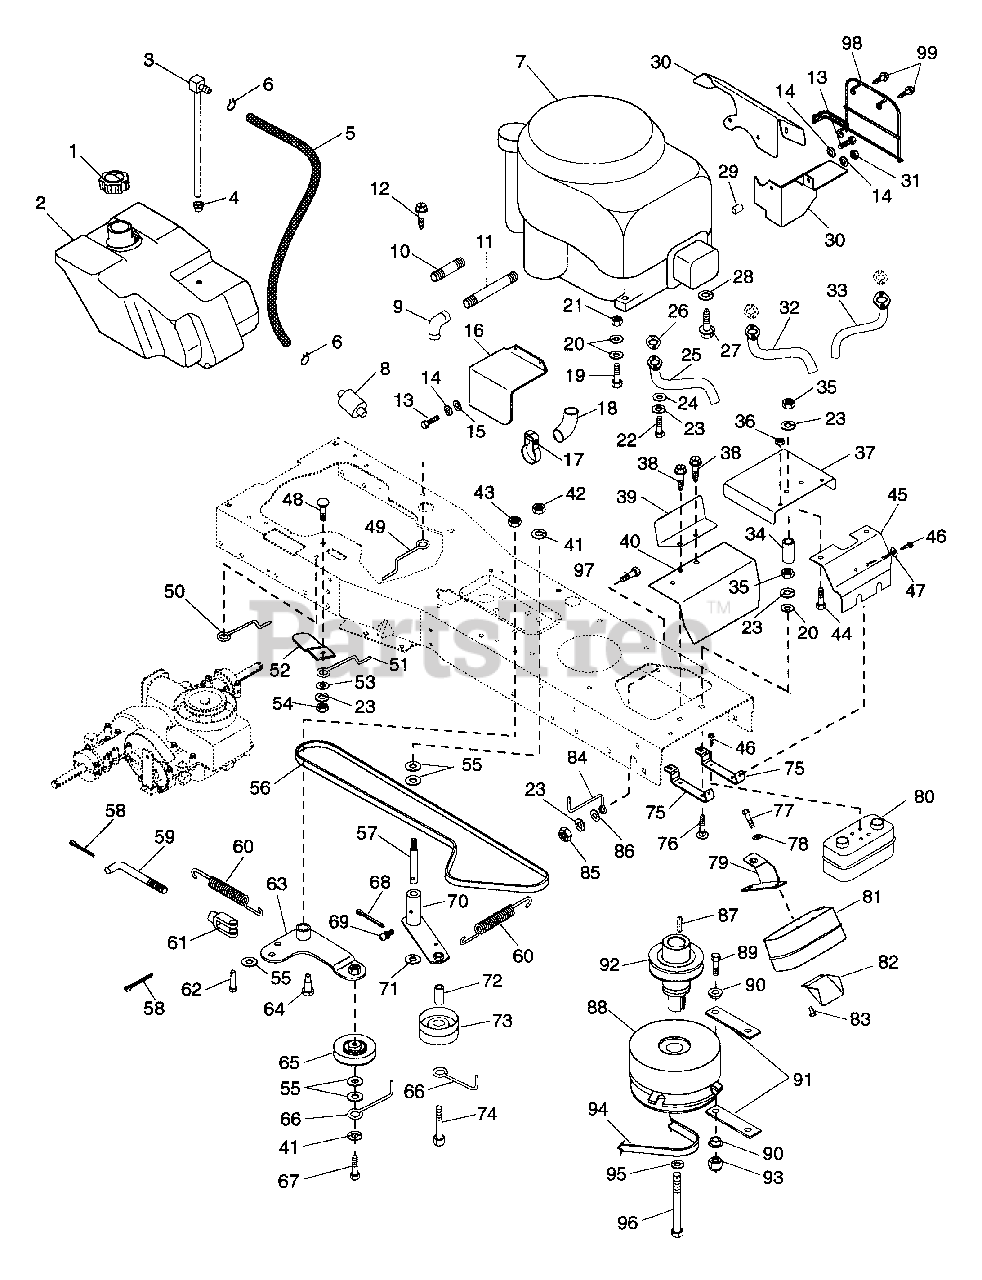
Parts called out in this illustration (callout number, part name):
1	FUEL CAP
2	FUEL TANK
3	TANK FITTING
4	BSHG-FLG .375 X 1.062 X .625 R
5	HOSE- FUEL LINE 34.00"
5	HOSE- FUEL LINE 40.50"
6	CLAMP-HOSE WIR.490/.510X.092#8
7	ENGINE- 12.0 OHV TEC
7	ENGINE- 14.0 OHV B&S I/C QUIET
7	ENGINE- 13.0 TEC OHV
7	ENGINE- 15 TEC OHV
7	ENGINE- 16.5 TEC OHV
7	ENGINE- 16.0 B&S VANGUARD TWIN
7	ENGINE- 12.0 B&S I/C
8	FUEL FILTER
9	ELBOW .375-18 NPTF
10	NIPPLE
11	NIPPLE
12	SCR-TAP .312-18X.75 HWH PL TR
13	BLT-HEX .25-20X.75 PL GR2
14	WSHR-LK .250X.077 HVY PL
15	WSHR-FL-STL.312X.734X.065PL
16	HEAT SHIELD
17	CLAMP, MUFFLER 1.38
18	PIPE
19	BLT-HEX .31-18X1.50 PL GR5
20	WSHR-FL-STL .328X.875X.062 PL
21	NUT-LK-TOP .312-18 GR C PL
22	SCR-CAP .31-18X.75 S/HD
23	WSHR-LK .312X.097 PL HVY
24	WSHR-FL-STL .323X.625X.062 PL
25	EXHAUST TUBE WELDT- 12.5/13HP
25	EXHAUST TUBE WELDT- 15/16.5HP
26	GASKET- 12.5/13 TEC (#35-414)
26	GASKET:15-16.5HP TEC (#35-438)
27	SCR-TAP .375-16X1.25 HWH PL TR
28	WSHR-LK-EXT .375X.050
29	SPACER BUSHING .5 X .32 X .21
30	HEAT SHIELD- SIDE 12B&S
30	HEAT SHIELD
31	NUT-HEX .250-28 YWZC
32	PIPE- EXHAUST R.H.
33	PIPE- EXHAUST L.H.
34	SPACER .334X.500X1.12
35	NUT-HEX .312-18
36	NUT-LK-CTR .250-20 PL
37	SHIELD- REAR HEAT 16B&S
38	SCR-TAP .312-18X.75 HWH PL TR
39	SHIELD
40	HEAT SHIELD
41	WSHR-LK .375X.094 MED PL
42	NUT-HEX .375-16
43	NUT-LK-CTR .375-16 GR A PL
44	BLT-HEX .25-20X.50 PL GR5
45	SHIELD- FRONT HEAT 16B&S
46	SCR-TAP 12-24X.50 HWH PL TR
47	WSHR-FL-STL.281X.62X.065 PL
48	BLT-RDHDSQNK .31-18X1.00 PL
49	BELT FINGER
50	BELT FINGER
51	BELT FINGER
52	BRACE
53	WSHR-FL-STL.344X.688X.065PL
54	NUT-HEX .312-18
55	WSHR-FL-STL .390X.750X.125 PL
56	V-BELT, HA-WRAPPED
56	V-BELT, 4L-RAW EDGE
57	SHOULDER STUD
58	PIN-COTR .09X.75 PL
60	SG-TENS .091X.56X5.07 WLD 30
61	YOKE, .312-24 X 2.25
62	PIN-CLEV .312X.822 HDND PL
63	IDLER PIVOT ARM
64	BLT-SHLDR .38-16X1.25
65	IDLER-V 3X.38
66	FINGER - BELT
67	BLT-HEX .38-16X1.75 PL GR2
68	PIN-COTR .18X1.25 PL
69	FTG-LUBE .25-28X.256 YWZC
70	IDLER PIVOT ARM
71	WSHR-FL-STL .520X.827X.062 YZ
72	TUBE .380 X .625 X 1.620
73	IDLER-FLAT 2.75X.38 PAINTED
74	BLT-HEX .38-16X3.50 PL GR5
75	BRACKET - MUFFLER
76	BLT-RDHDSQNK.31-18X2.25 PL
77	BLT-HEX .25-20X.50 PL GR5
78	WSHR-LK .250X.077 HVY PL
79	BRACKET
80	MUFFLER W/ DEFLECTOR
81	MUFFLER ASSY
82	DEFLECTOR- MUFFLER
83	SCR-TAP 8-32X.38 SL HWH PL 23
84	BELT FINGER
85	NUT-HEX .312-18
86	WSHR-FL-STL.312X.734X.065PL
87	KEY-SQ .25 X 1.25 X .25 SAE
88	ELECTRIC CLUTCH/BRAKE(1.8AMP)
88	ELECTRIC CLUTCH/BRAKE (3.4AMP)
89	BLT-HEX 10-24X1.00 PL GR2
90	SPECIAL WASHER
92	SHEAVE EXTENSION SHAFT-GEAR
92	SHEAVE EXTENSION SHAFT- HYDRO
93	NUT-LK 10-24 NY PL
94	V-BELT, 4L-RAW EDGE
95	WSHR-LK .438X.133 HVY
96	SCR-CAP .44-20X4.00 GR5 HHPL
97	BLT-HEX .31-18X1.00 PL GR 2
98	MUFFLER GUARD
99	SCREW (B&S#094887)
